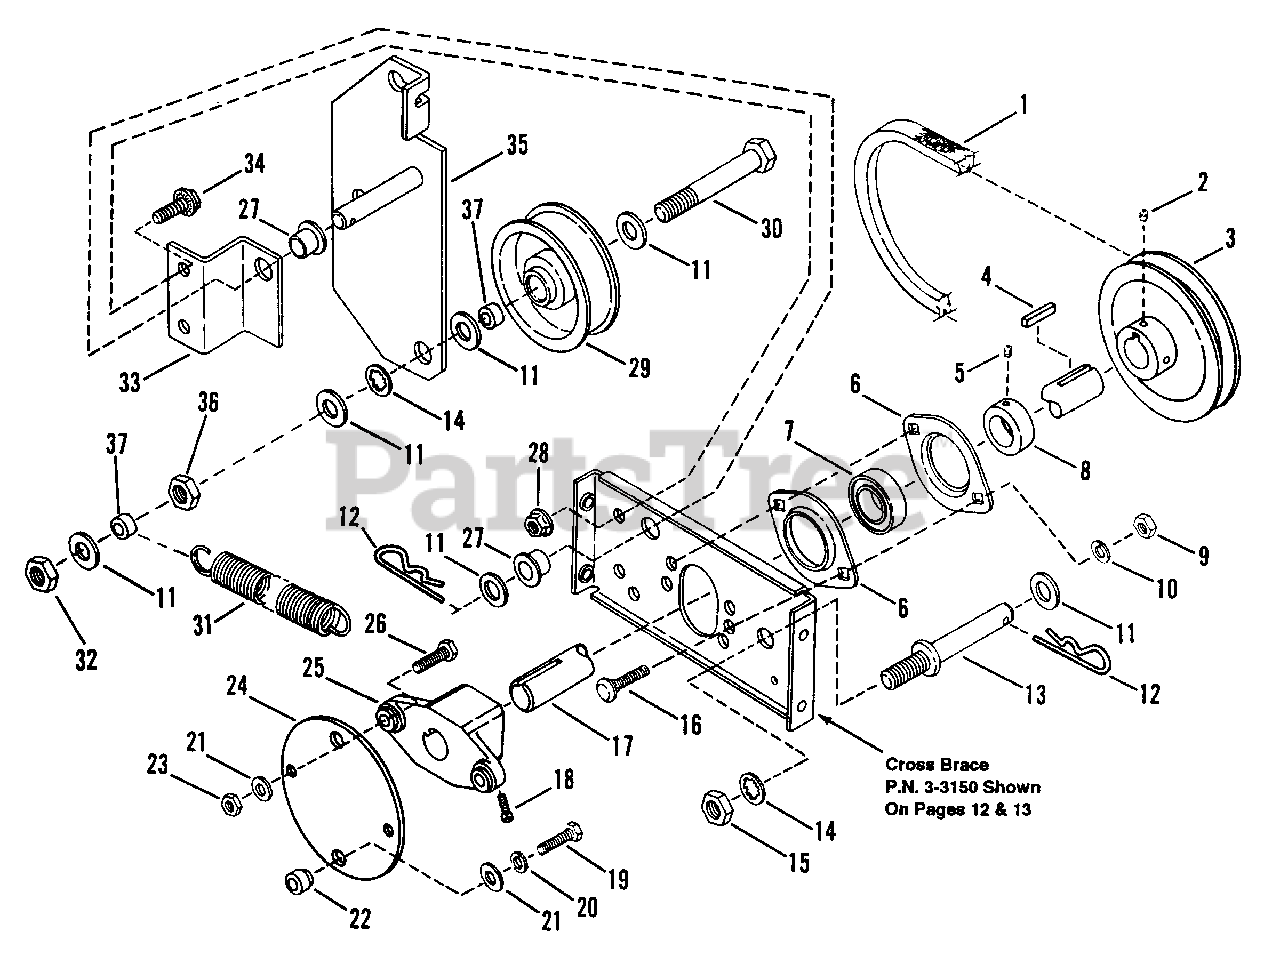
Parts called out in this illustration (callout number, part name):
1	BELT, Traction Drive
2	SCREW, 5/16-18 x 5/16" Socket Head
3	PULLEY, Drive, 4.25" O.D.
4	KEY, Drive Pulley, 3/16 x 3/16 x 1"
5	SCREW, 1/4-20 1/4" Socket Head
6	FLANGETTE
7	BEARING
8	COLLAR, Lock
9	NUT, 5/16-18 Hex
10	WASHER, 5/16 Split Lock
11	WASHER, 3/8 SAE Flat
12	HAIRPIN, 1/4 x 1-1/8"
13	STUD, Idler
14	WASHER, 3/8 Internal Tooth Lock
15	NUT, 3/8-24 Hex, Grade 2
16	BOLT, 5/16-18 x 3/4 Carriage
17	SHAFT, Drive
18	SCREW, 5/16-18 x 1/2" Square Head, Cup Point, Set
19	SCREW, 3/8-16 x 1-1/2" Hex Head Cap, Grade 5
20	WASHER, 3/8 Split Lock
21	WASHER, 13/32" I.D., 3/4" O.D.
22	SPACER, Flex Coupling
23	NUT, 3/8-16 Hex, Center Lock
24	DISC, Flex Coupling
25	HUB, Flex Coupling
26	SCREW, 3/8-16 x 1" Hex Hd. Cap, Grade 2
27	BUSHING
28	NUT, 5/16-18 Hex Fl. Lock, Gr.5
29	PULLEY, Idler, 2.25 O.D.
30	SCREW, 3/8-24 x 2" Hex Hd. Cap, Gr.5
31	SPRING
32	NUT, 3/8-16 Hex Lock, Grade 5 or B
33	BRACKET, Idler Arm Support
34	BOLT, 5/16-18 Hex Flange Lock
35	ARM, Idler
36	NUT, 3/8-16 Hex, Grade 5 or B
37	SPACER
